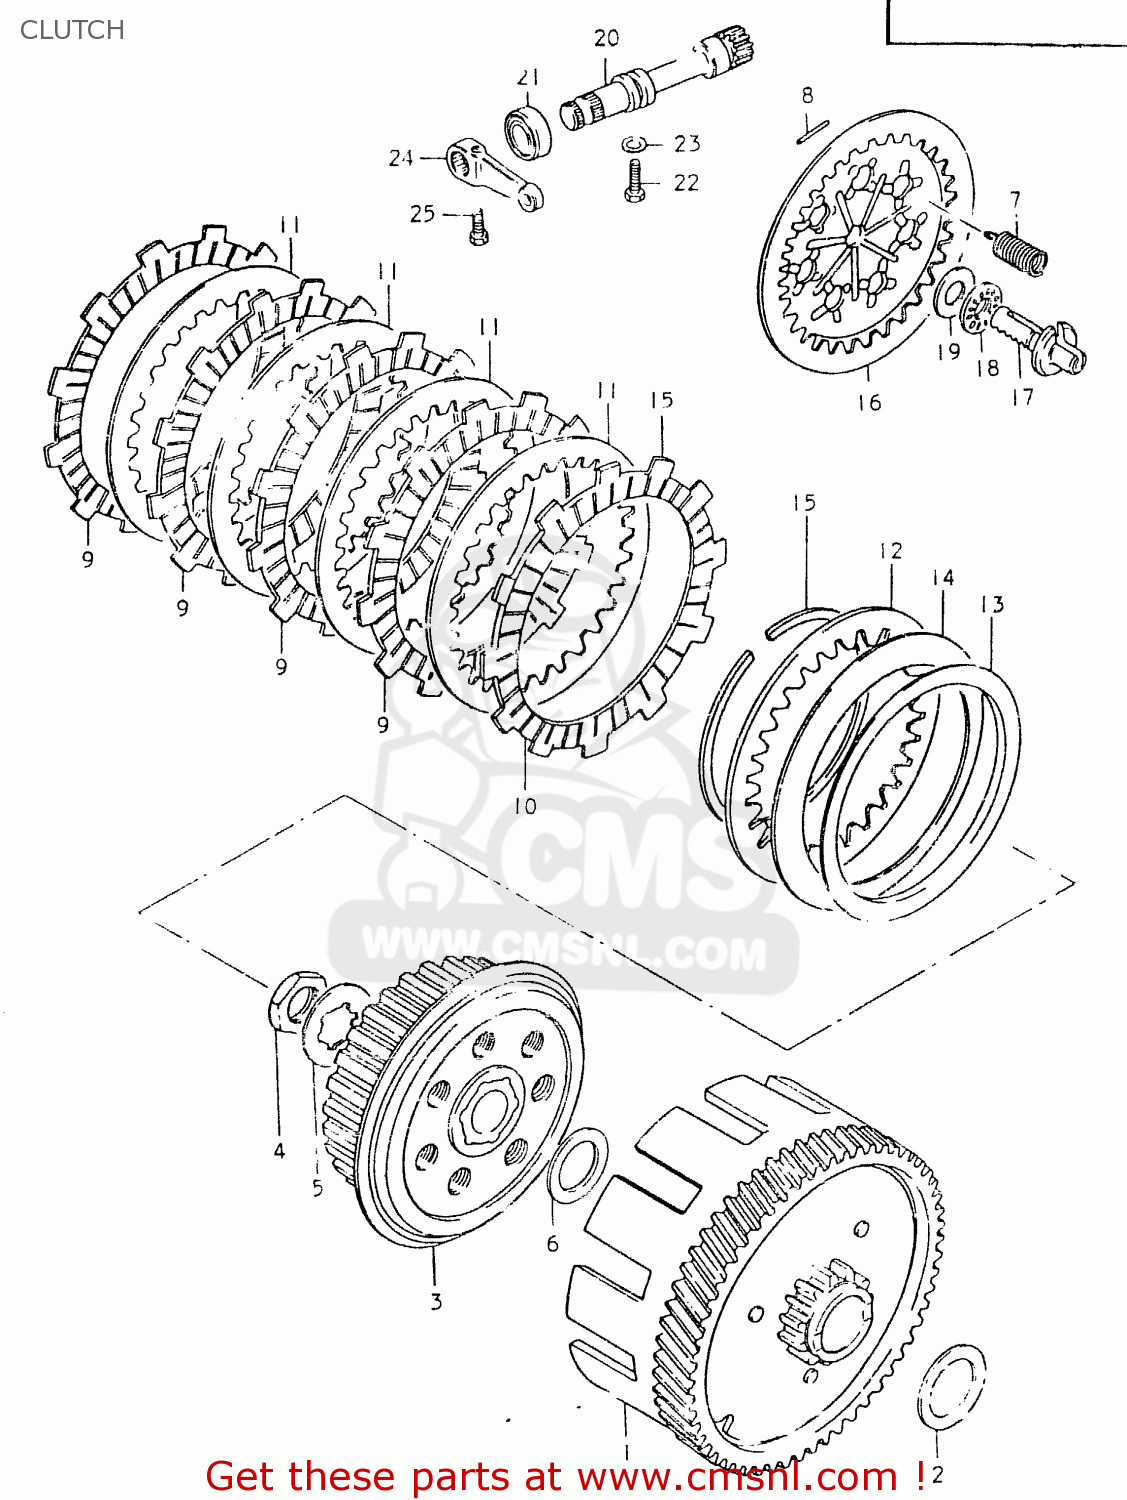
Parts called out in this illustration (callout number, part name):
1	GEAR ASSEMBLY,PRIMARY DRIVE
2	WASHER
3	HUB,CLUTCH SLEEVE
4	NUT
5	WASHER,LOCK
6	WASHER
7	SPRING
8	PIN(2.5X19.8)
9	PLATE,CLUTCH DRIVE
10	PLATE,CLUTCH DRIVE (MCA)
11	PLATE,CLUTCH DRIVEN (NAS)
12	PLATE,CLUTCH DRIVEN(T:2.0) (NAS)
13	SEAT,WAVE WASHER
14	WASHER
15	CIRCLIP
16	PLATE,CLUTCH PRESSURE
17	BACK,CLUTCH RELEASE
18	BEARING(10X22X2.8)
19	WASHER(10.1X21.4X0.8)
20	PINION,CLUTCH RELEASE
21	OIL SEAL
22	BOLT(6X12)
23	WASHER
24	ARM,CLUTCH RELEASE
25	BOLT
